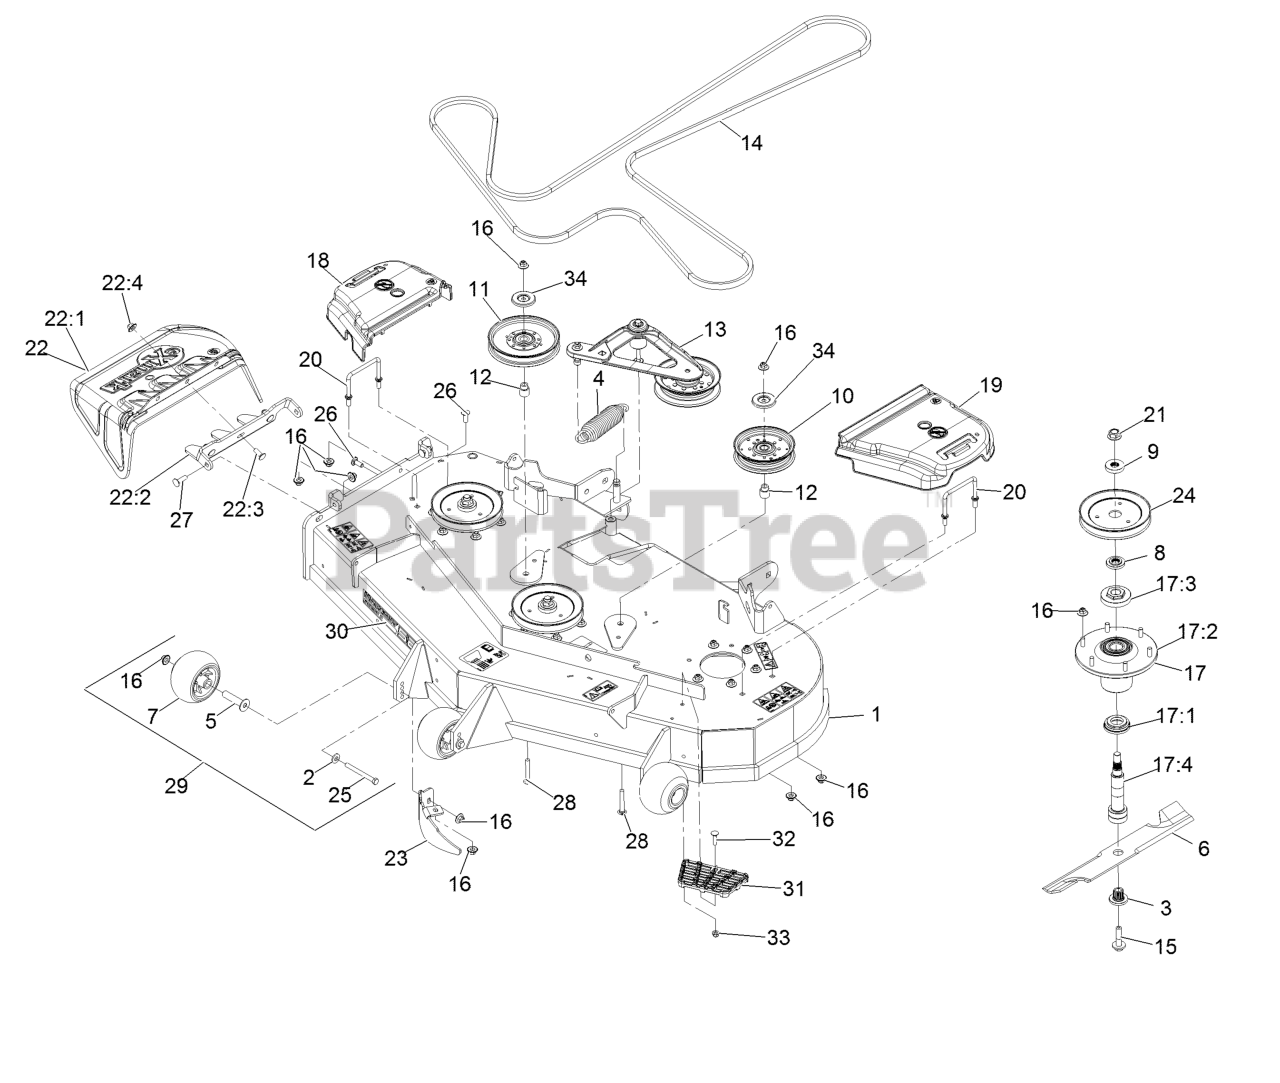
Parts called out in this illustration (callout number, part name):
1	ASM,Deck W/ Decals 52
2	Washer-Spring Disc 3/8
3	Bushing, Splined
4	Spring-Extension
5	Axle, Roller
6	Blade, Solid
6	Blade, Low Lift
6	Blade, Mulching
6	Blade-Notched
6	Blade-Extreme 2, 18.00"
7	Roller-Anti-Scalp
8	Spacer, Splined Stepped
9	Spacer, Splined
10	Pulley-Idler, Flat
11	Idler-Pulley
12	Bushing, Idler
13	Deck Idler ASM
14	Belt,V-B X 186.00"
15	Screw-Sems 1/2-20 X 2.19
16	Nut-Nyloc 3/8-16 Flg
17	ASM,Spindle Housing
17:1	Guard, Bottom
17:2	Asm, Cutter Housing
17:3	Nut, Spindle 7/8-14
17:4	Spindle,Double Spline
18	Cover-Belt, RH
19	Cover-Belt, LH
20	Wireform-Cover
21	Nut-Flange 5/8-18 Centerlock
22	ASM,Discharge Chute
22:1	Chute, Discharge
22:2	Bracket,Discharge Chute
22:3	Bolt-Carriage 3/8-16 X 1
22:4	Nut-Nyloc 3/8-16 Flg
23	Baffle-Dogleg, Lz-Vt52
24	Sheave,Blade Drive
25	Screw-HH 3/8-16 X 3 3/4 GR 8
26	Bolt-Carriage 3/8-16 X 1
27	Bolt-Carriage 3/8-16 X 1 1/4
28	Bolt-Carriage 3/8-16 X 2 1/2
29	Kit, Anti-Scalp Roller
30	Decal, 526
31	Step-Deck
32	Bolt-Carriage 5/16-18 X 1 1/4
33	Nut-Nyloc 5/16-18 Flg
34	Shield-Dust
